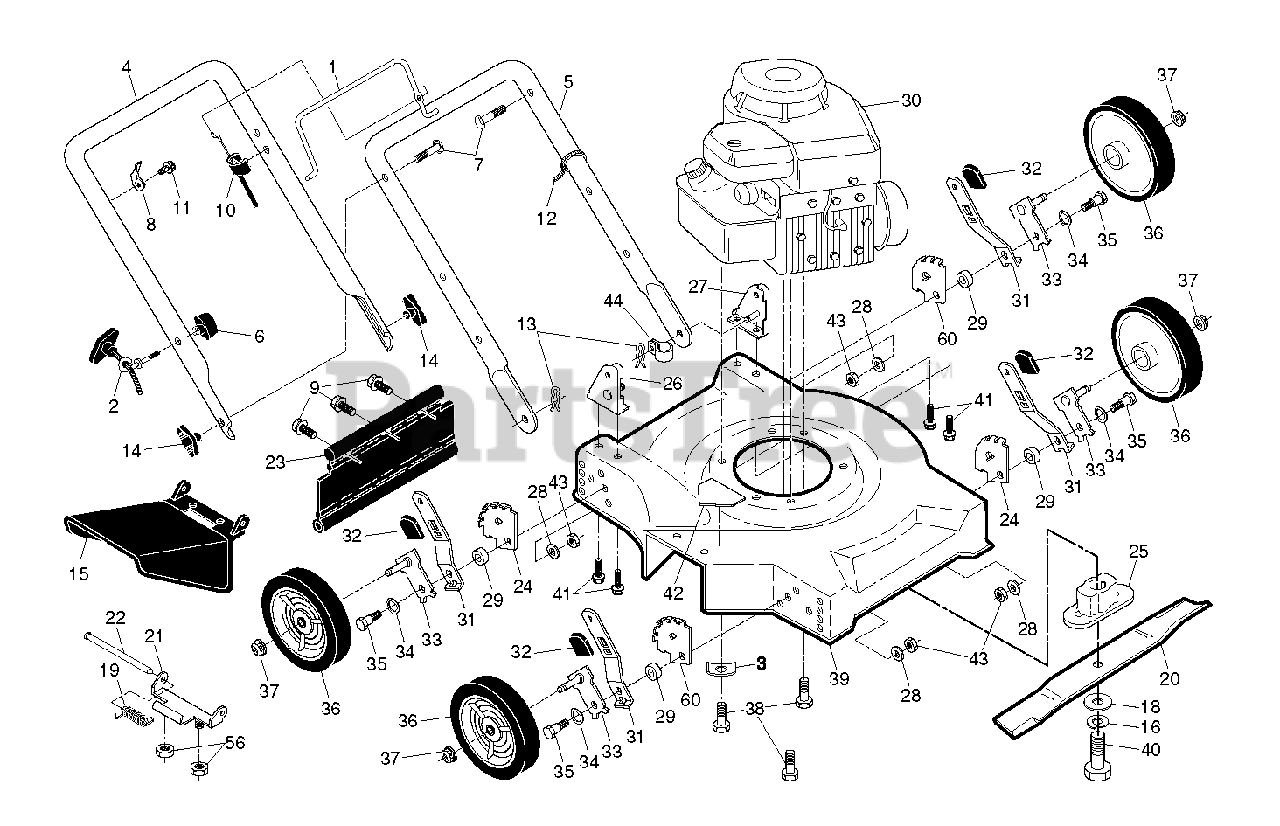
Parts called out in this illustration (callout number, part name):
1	BAIL.CONT.D.STRAIGHT.PUSH.BLK
2	Rope Guide, Blk Zinc Chrom
3	WASHER.ENGINE.BZP
4	HANDLE.UPPER.FGD/PUSH.BLACK
5	LOWER HANDLE
6	T-KNOB.NEW ROPE GUIDE
7	BOLT, HANDLE 5/16-18X1.75
8	BRACKET.UPSTOP.RT
9	SCREW.HEX.WASH.HD.TAPPING
10	CABLE.MZR.RATO.22"LOW.
12	TIE GUIDE
13	HAIRPIN COTTER
15	GUARD.DISCHARGE.ECON.BLK.US/CE
18	WASHER,HARDEN
19	SPRING.SIDE.DISCHARGE
20	Mower Blade, 20" Mulching
21	HINGE DEFLECTOR
22	HINGE ROD
23	SKIRT.ECON.20.SD.WHL.ADJ
24	WHEEL ADJ BRACKET FRONT
25	ADAPTOR.BLADE.7/8
26	HANDLE BRACKET ASM. RH
27	HANDLE BRACKET ASM. LH
28	WASHER
29	SPACER.HEIGHT.ADJUSTER
31	SELECTOR SPRING, FRONT
33	AXLE ARM ASSY.
34	WASHER.CURVED.CYLINDRICAL
35	SHOULDER BOLT 5/16-18
36	WHEEL.7X1.5.DMD.3SPK.BLACK.
37	NUT.HEX.FLANGE.3/8-16.LOCKNUT
38	BOLT 3/8-16X1-1/8
39	KIT.HSG.20SD.PUSH.MS665.TRI
40	SCREW, HEX HD 3/8-24 X 1-3/8
41	SCREW.5/16-18X3/4
42	No Step Decal
43	NUT.71038.31-18.HEX.NYLOCK
44	CLIP.CABLE.BLK
56	LOCKNUT.NYLOC.1/4-20
60	WHEEL ADJ BRACKET FRONT
